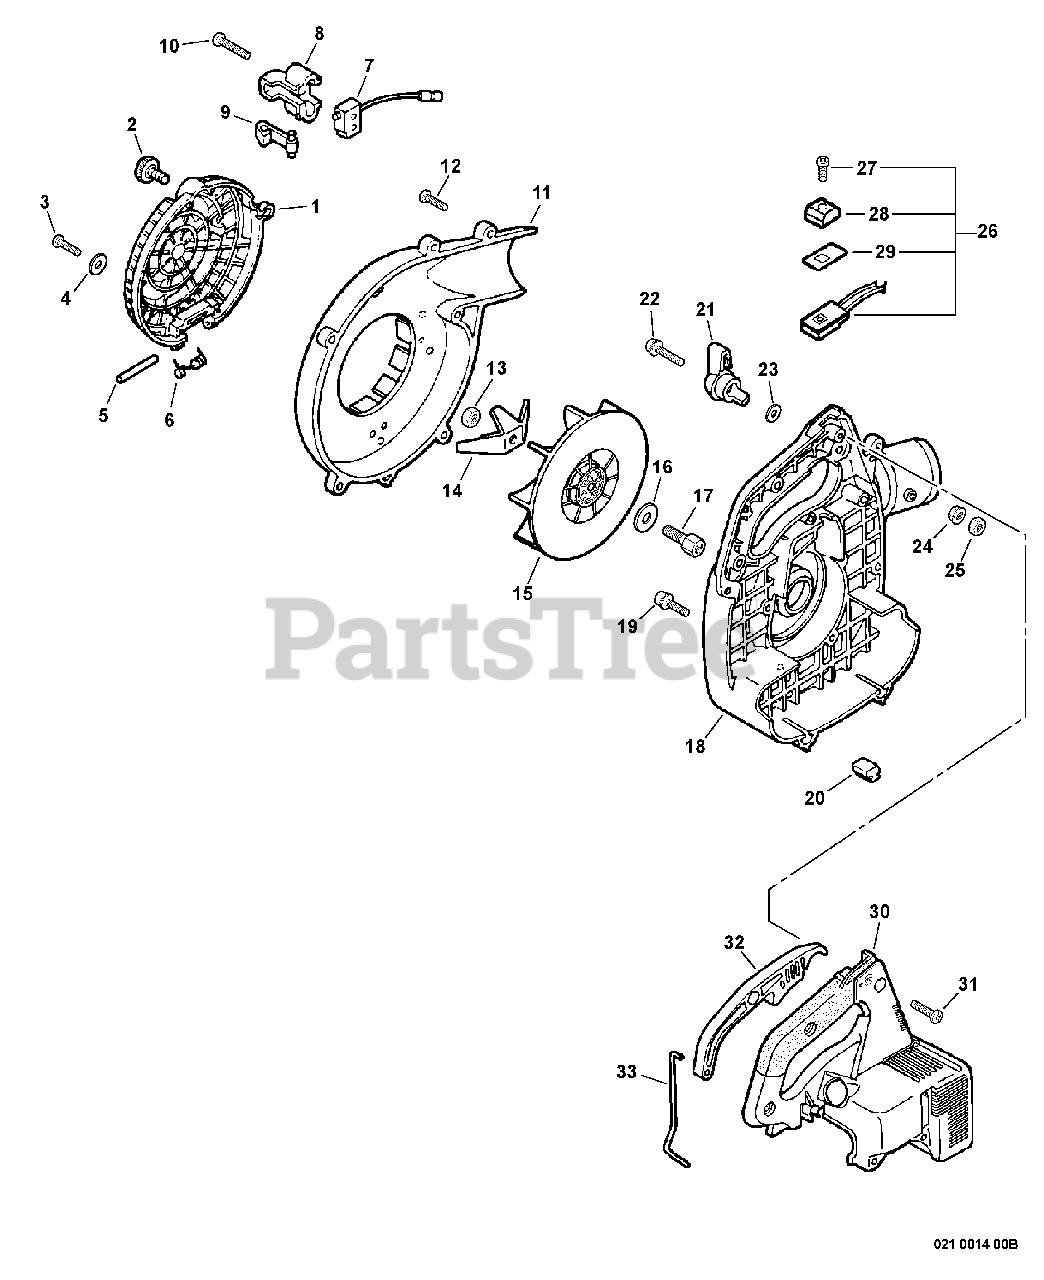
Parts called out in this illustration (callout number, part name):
1	COVER, INTAKE
2	THUMBSCREW
3	SCREW 5×14
4	WASHER 5.5×12×0.8
5	PIN, INTAKE COVER
6	SPRING, COIL
7	SWITCH, INTERLOCK
8	BRACKET, SHUT OFF SWITCH
9	LEVER, ACTUATOR
10	SCREW 4×22
11	COVER, FAN
12	SCREW, TAPPING 5×20
14	SHREDDER
17	HUB, FAN
18	CASE, FAN
19	SCREW 4×22
21	LEVER, CRUISE CONTROL
22	SCREW 5×25
23	WASHER 5.5×12×0.8
24	NUT, FLANGE M5
26	CABLE ASSY, CONTROL
27	SCREW 3×10
28	SWITCH, ON-OFF
29	LABEL, SWITCH
30	COVER, ENGINE
31	SCREW, TAPPING 5×20
32	TRIGGER, THROTTLE
33	ROD, THROTTLE
